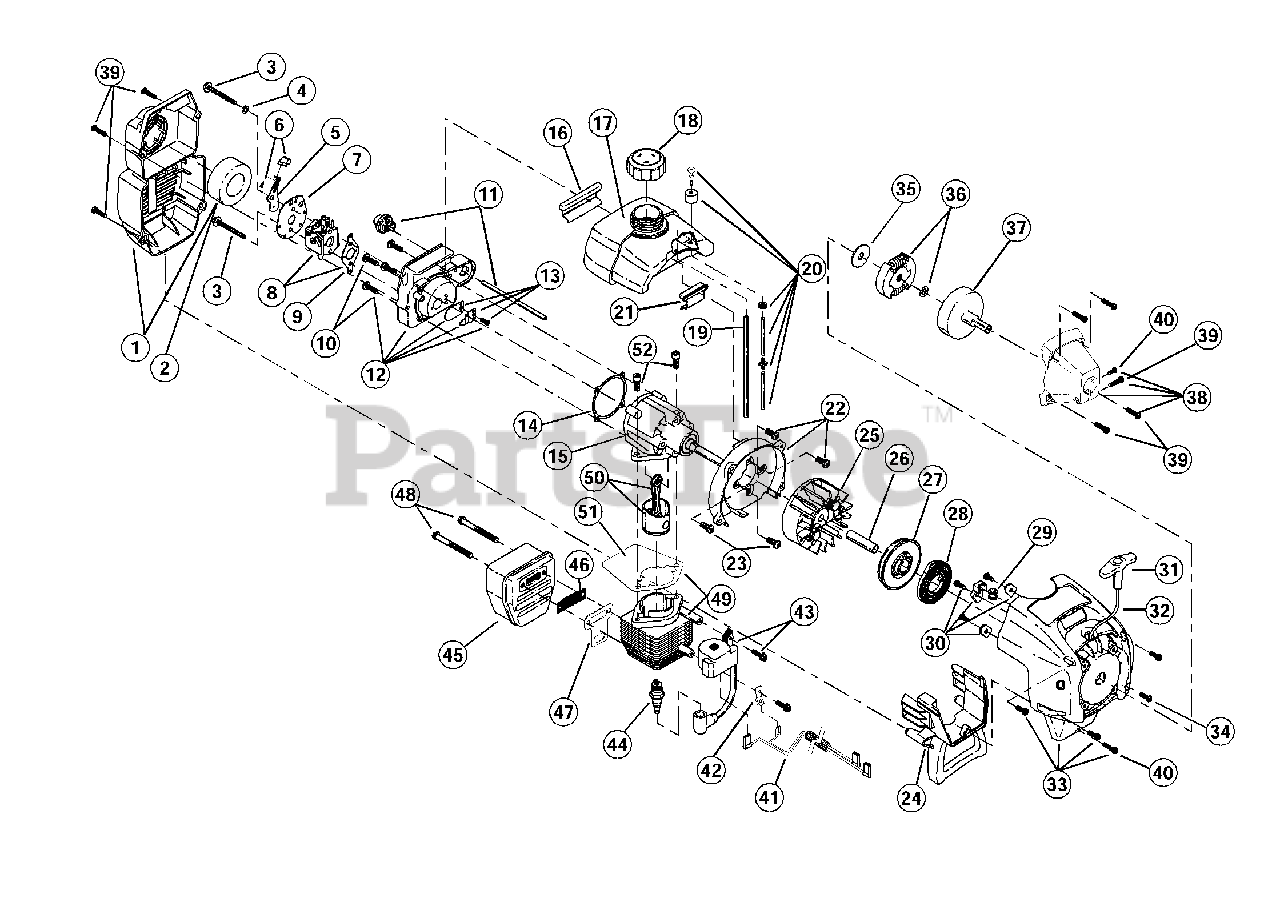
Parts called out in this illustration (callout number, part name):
1	Air Cleaner/Muffler Cover Assembly
2	Air Cleaner Filter
3	Carburetor Mounting Screw Assembly
4	Wavey Washer
5	Choke Lever Assembly
6	Choke Knob and Screw
7	Choke Plate Assembly
8	Carburetor Assembly W/Limiter Caps
9	Carburetor Gasket
10	Carb Mount Screw
11	Primer and Hose Assembly
12	Carb Mount Assembly
13	Reed Assembly
14	Carburetor Mount Gasket
15	Crank Case Service Assembly
16	Rear Mounting Pad
17	Fuel Tank Assembly
18	Fuel Cap Assembly
19	Fuel Return Line
20	Fuel Line Assembly
21	Front Mounting Pad
22	Shroud Assembly
23	Shroud Screw
24	Shroud Extension & Stand
25	Flywheel Assembly
27	Recoil Pulley Assembly
28	Recoil Spring
29	Rope Guide
30	Pulley Retainer Assembly
31	Pull Handle
33	Starter Housing Assembly
34	Housing Screw
35	Clutch Washer
36	Clutch Rotor Assembly
37	Clutch Drum Assembly
38	Clutch Cover Assembly
39	Cover Screw
40	Anti-Rotation Screw
41	Wire Leads and Sleeve
41	Ground Tab
43	Module Assembly
44	Spark Plug
45	Muffler Assembly
46	Spark Arrestor Screen
47	Exhaust Gasket
48	Muffler Mounting Bolt Assembly
49	Cylinder Assembly
50	Piston and Rod Assembly
51	Cylinder Gasket
52	Cylinder Bolt
